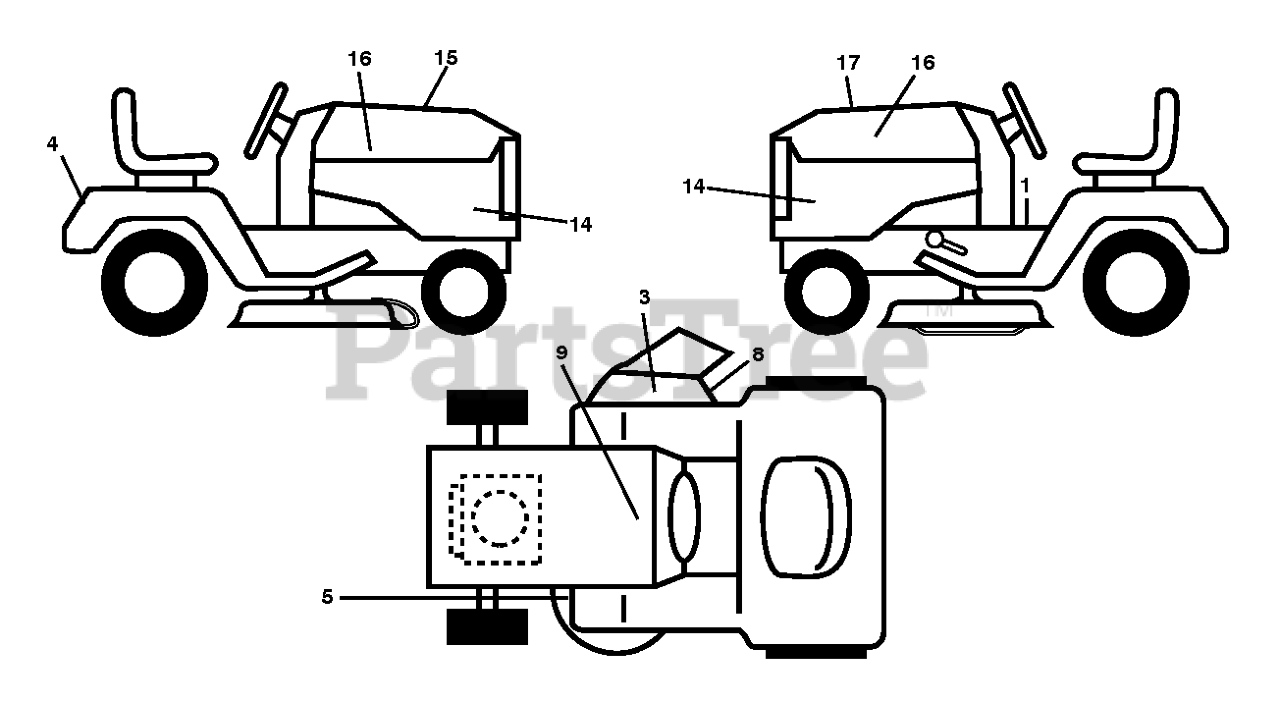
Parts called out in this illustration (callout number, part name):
1	DECAL.WARN.STARTINST.LOWEARIEN
2	DECAL.MOWER.WARN.KEEP.HAND.AWY
4	DECAL.FENDER
5	DECAL.MOWER.CAUTION.TENSION.AR
8	DECAL.MOWER.SCH.48/54.PREM
9	DECAL BTRY SYMBOLS
14	DECAL.SIDE.PANEL.LGT2654.2013
15	DECAL.WARNING.CUST.RESP.E85.
16	DECAL.BADGE.170MM.TEXTLOGO.
17	DECAL.RPL.KH.KT7000.TGW.54.K46
